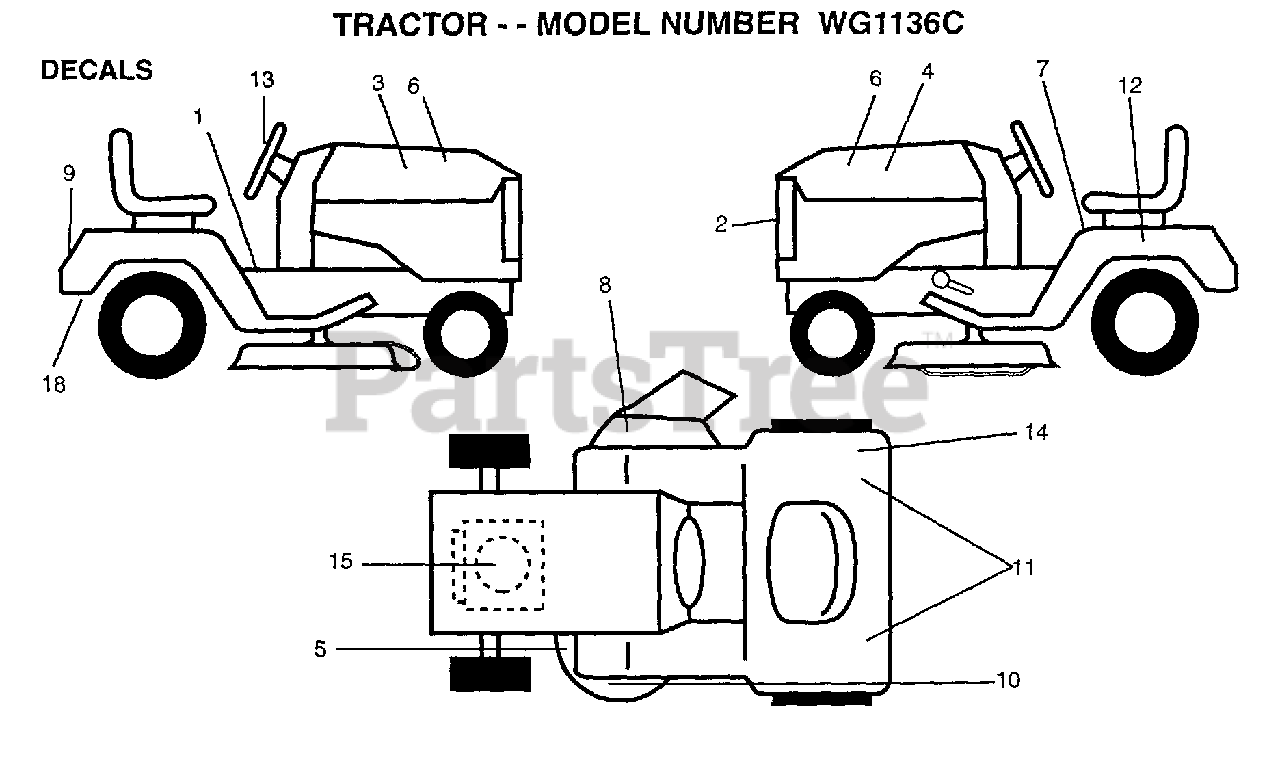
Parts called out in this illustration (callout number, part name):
1	DECAL.OP.INST.SYM
2	"DECAL,LIGHT BOX"
3	DECAL STRIP HD RH
4	DECAL STRIP HD LH
5	DECAL.V.BELT
6	DECAL.PNL.SIDE.
7	DECAL.READ.O.MANU
8	DECAL.DANGER.CUTF
9	DECAL.FENDER
10	DECAL.MOWER
11	DECAL.FEND.QUICKS
12	DECAL.BTRY.DANGER
13	DECAL.WHL.STRG.
15	DECAL, HP, ENGINE
18	DECAL.EURO.ST.CE.
